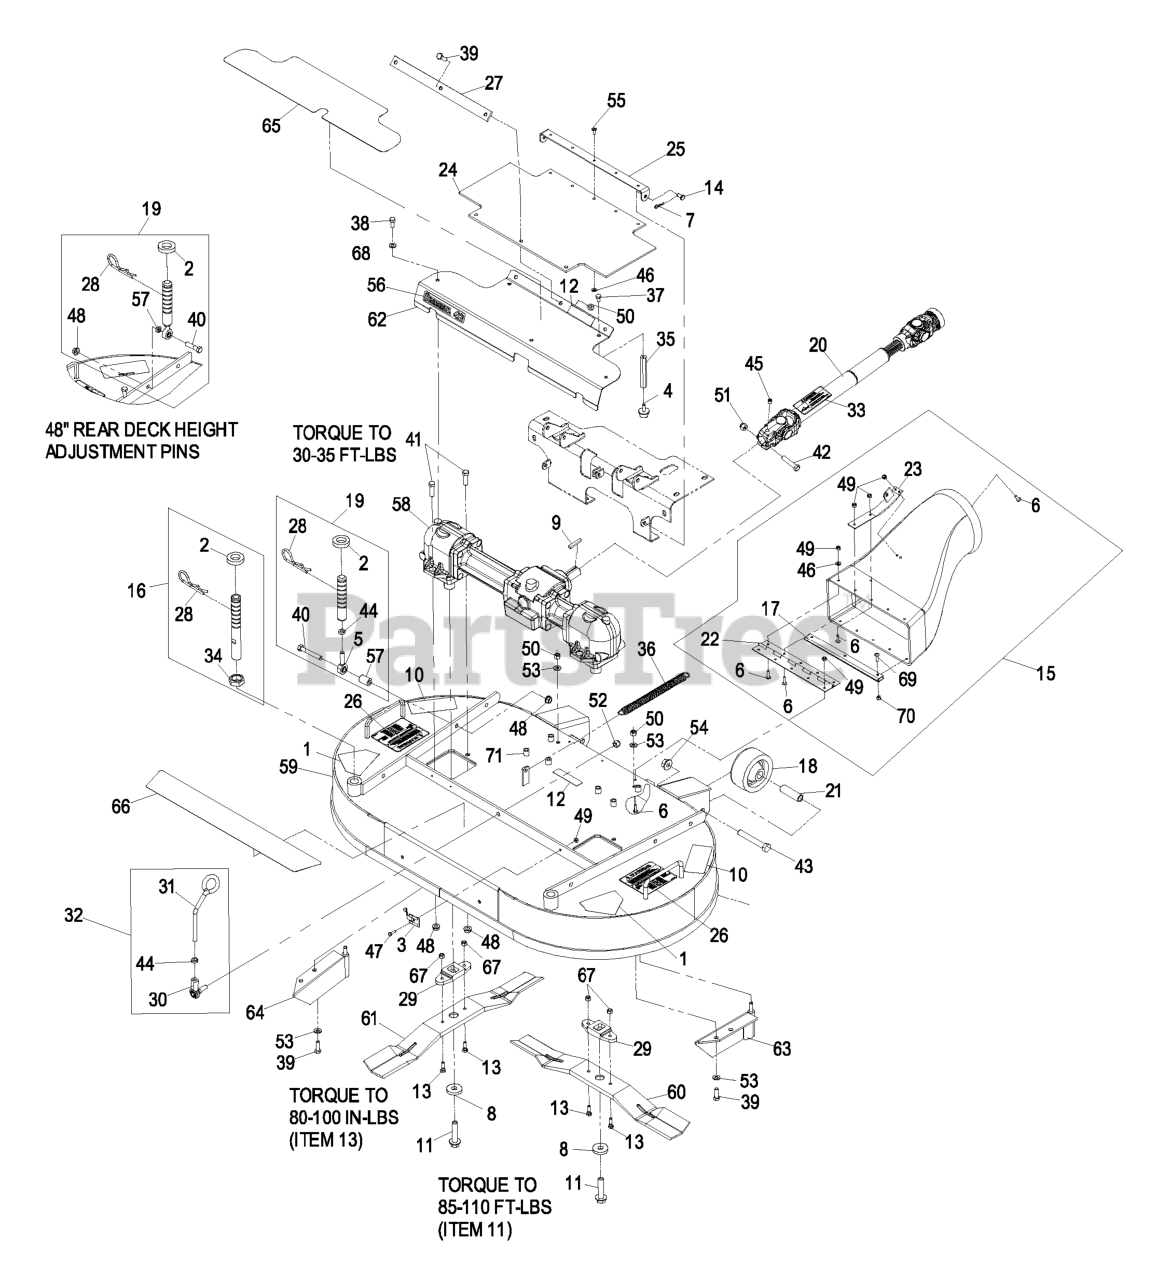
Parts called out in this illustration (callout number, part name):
1	DECAL-DANGER
2	SPACER-DECK SUPPORT
3	CLIP-DECK, HOLD UP ROD
4	BUMPER-RUBBER
5	BALLJOINT
6	SCREW-HEAD, TRUSS
7	PIN-COTTER
9	KEY-SQUARE
10	DECAL-TORQUE
11	BOLT-BLADE
12	DECAL-COVER, MISSING
13	BOLT-SHEAR
14	PIN-CLEVIS
15	DISCHARGE TUBE ASM
16	FRONT DECK HEIGHT ADJUST
17	GUARD-PLENUM
18	ROLLER-DECK
19	REAR DECK HEIGHT ADJUST A
20	DRIVE SHAFT ASM
21	SPACER-ROLLER
22	HINGE-PIANO
23	MOUNT-SPRING
24	GUARD-PTO
25	BRACKET-GUARD, PTO
27	STRAP-DRIVE, LINE COVER
28	PIN-CUT HEIGHT
29	DRIVER-BLADE
30	BALLJOINT-RH
31	LATCH-DECK
32	DECK LATCH ASM
33	DECAL-DRIVELINE
34	NUT-JAM
35	STAND-OFF
36	SPRING-EXTENSION
37	SCREW-HH
38	SCREW-HH
39	SCREW-HH
40	SCREW-HH
41	SCREW-HH
42	SCREW-HH
43	SCREW-HH
44	NUT-HEX
45	SCREW-SET, HSH
46	WASHER-FLAT
48	NUT-HHF, WHIZ
49	NUT-LOCK, NI
50	NUT-LOCK, NI
51	NUT-LOCK, NI
52	NUT-LOCK
53	WASHER-SPRING
54	NUT-HHF
55	RIVET-BLIND
56	DECAL,COMMERCIAL 42
57	TUBE-INTERLOCK
58	GEARBOX ASM
59	DECK ASM
60	BLADE,22 INCH LH
61	BLADE,22 INCH RH
62	ASM,GEARBOX COVER 42 W/DE
63	BAFFLE-LH
64	BAFFLE-RH
65	PAD-ANTI SKID
66	PAD-SKID, ANTI
67	NUT-LOCK, NI
68	WASHER-PLAIN
69	BOLT-CARR
70	NUT-LOCK, NI
71	NUT-CLINCH
